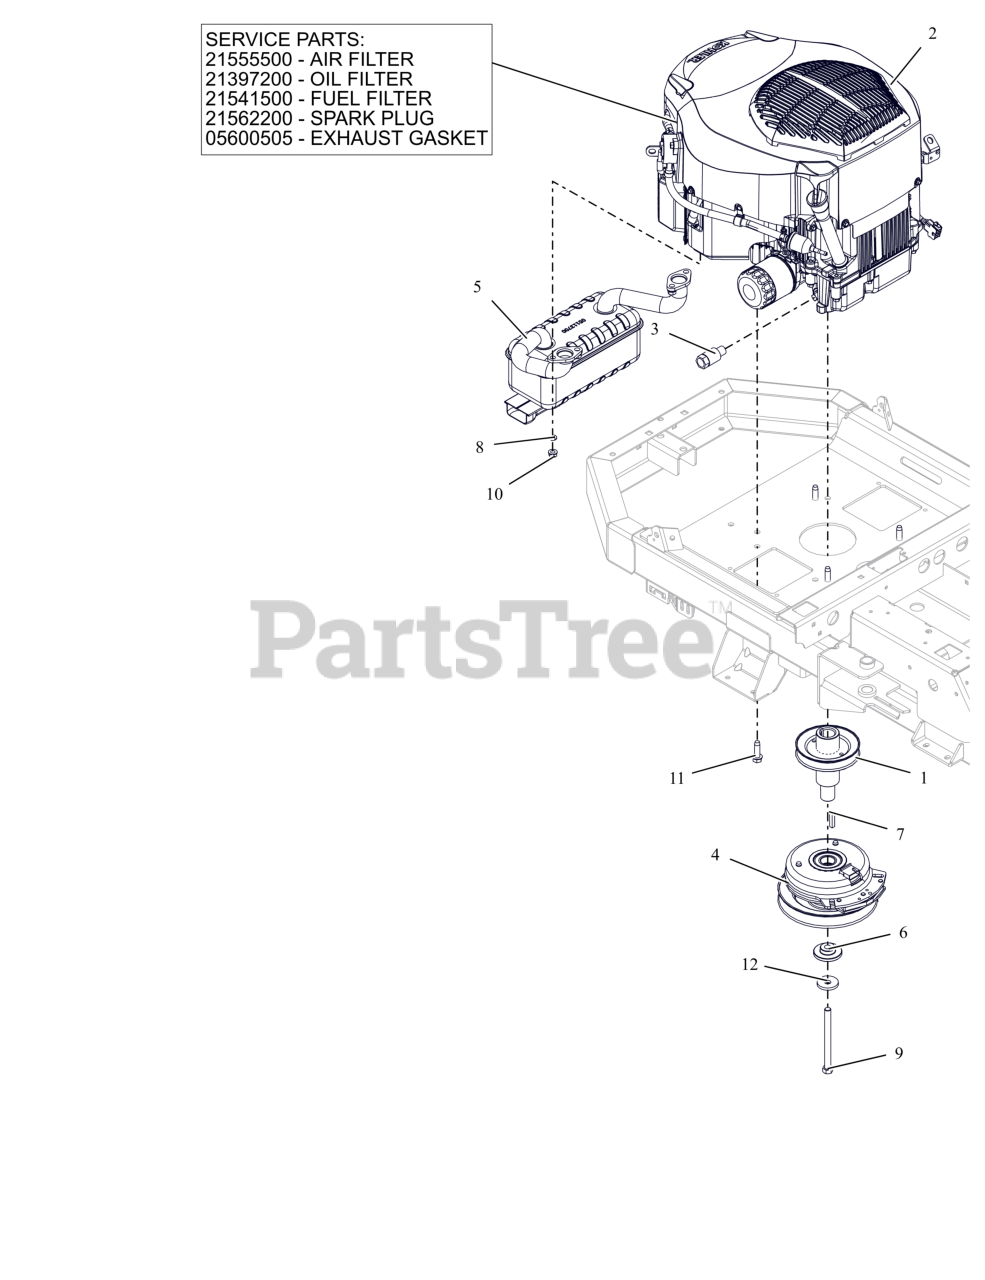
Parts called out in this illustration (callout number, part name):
1	WLDMT, DRIVE SHEAVE (LONG)
2	ENGINE, KOHLER 22HP TWIN
2	AIR CLEANER, KOHLER
2	FILTER, OIL - KOH CV20
2	FILTER, FUEL
2	PLUG, SPARK (RFI)
2	GASKET, MUFFLER COURAGE TWIN
3	DRAIN, OIL
4	CLUTCH,105FTLB MONOPOLE 6.83"
5	MUFFLER, KOHLER
6	BSHG-FLG .469X1.06X.574X2.0
7	KEY-SQ .25 X 1.25 X .25 SAE
8	WSHR,LK-REG .312X.078 ZCC
9	BLT, HEX .44-20X5.00 G8 ZCC NT
10	NUT-LK-TOP-FLG .312-18 GF ZCC
11	SCR,TAP .375-16X1.25HWH TR ZCC
12	WASHER, 7/16" SPRING DISK
